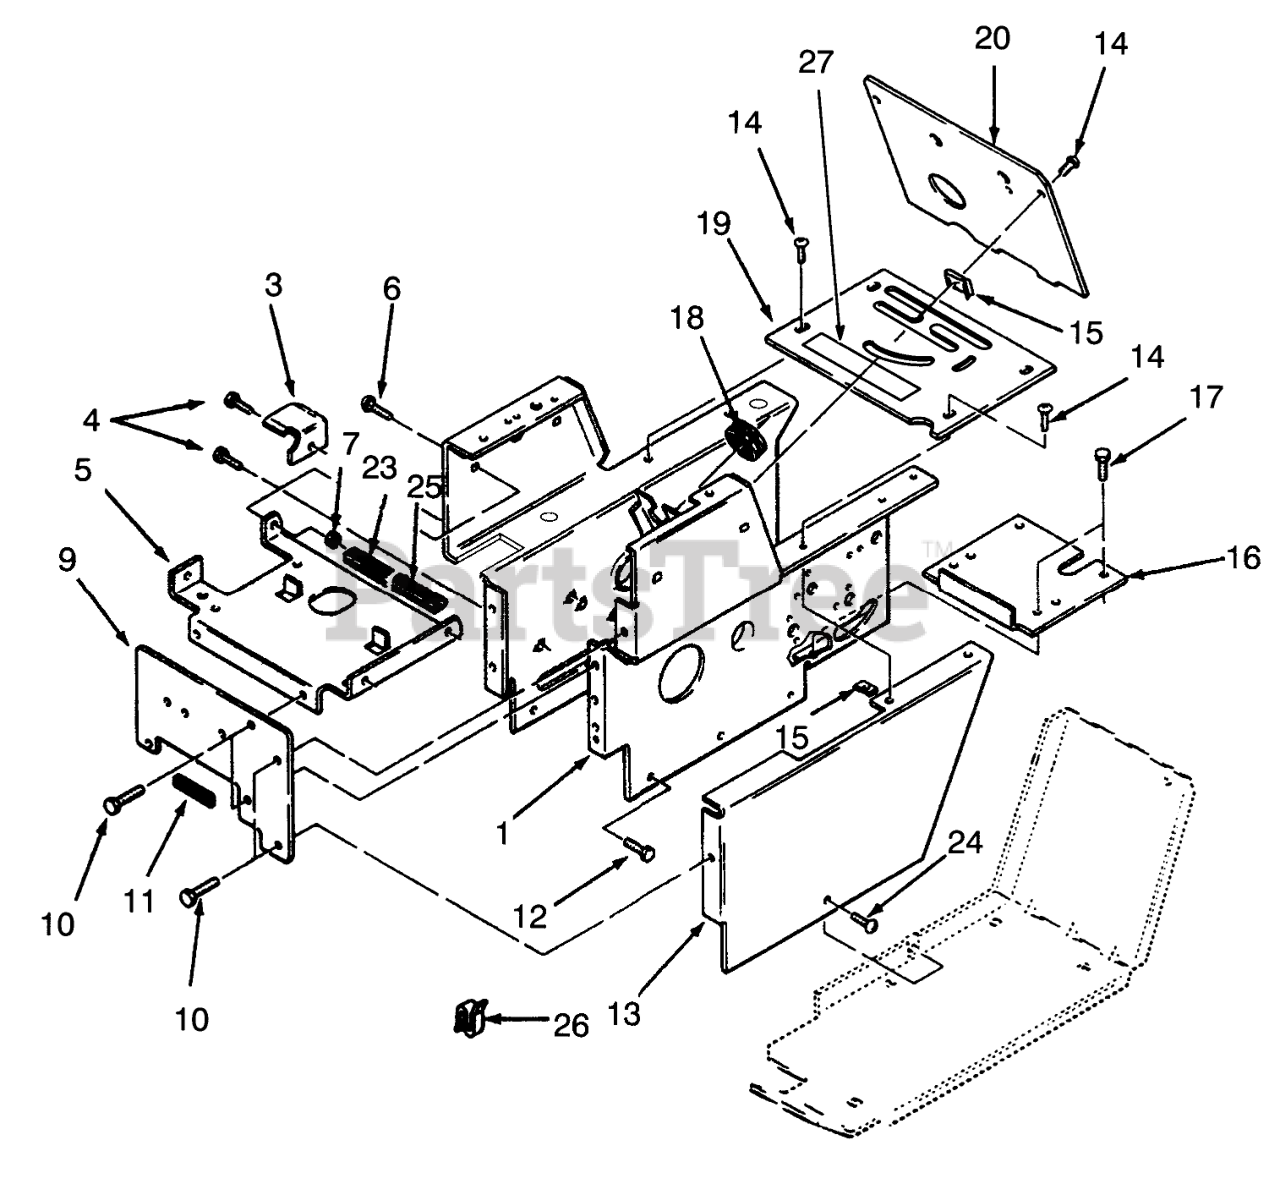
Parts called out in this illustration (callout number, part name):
1	Handstand
3	Bracket-Belt
4	Bolt
5	SUPORT-BATERYB
6	BOLT CARR. 5/16X1/2 BK
7	Nut
9	Front Plate
10	Bolt
11	EDGE TRIM 4IN OF 102896
12	Bolt
13	Cover-Side LH
14	SCREW-PPH
16	Cover-Dust
17	Bolt
18	GROMMET
19	Plate-Shift Cover (Incl. Ref. #27)
20	Plate-Hood Stand
23	EDGE TRIM 5" OF 102896
24	SCREW-PPH
25	EDGE TRIM 2" 102896
26	SPEED CLIP
27	DECAL-DANGER
